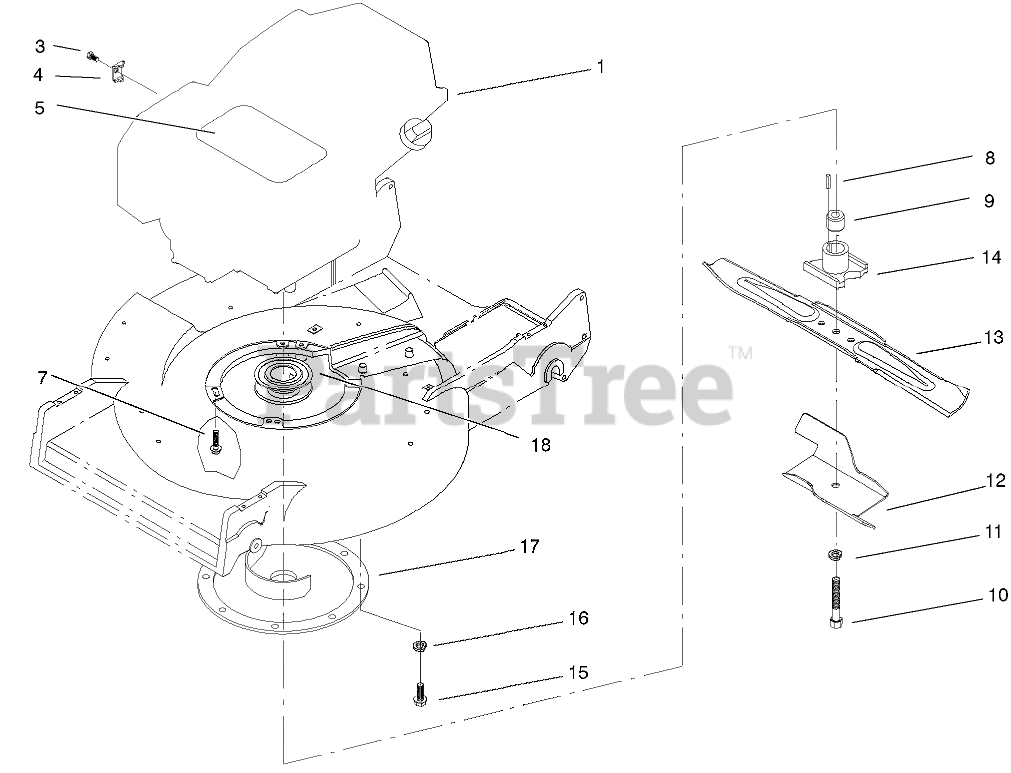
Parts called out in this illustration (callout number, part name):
1	Engine-4cyc Zs, Kawasaki
3	BOLT (5X18)
4	CLAMP
5	Decal-Engine
7	SCREW-MOUNT, ENGINE
8	KEY-SQUARE
9	SPACER-BLADE RETAINER
10	SCREW-BLADE
11	WASHER-LOCK
12	STIFFENER-BLADE
13	Blade
14	Retainer-Blade
15	SCREW-HWHTF
16	WASHER-LOCK, INTERNAL
17	PROTECTOR-CRANKSHAFT
18	PULLEY-DRIVER
